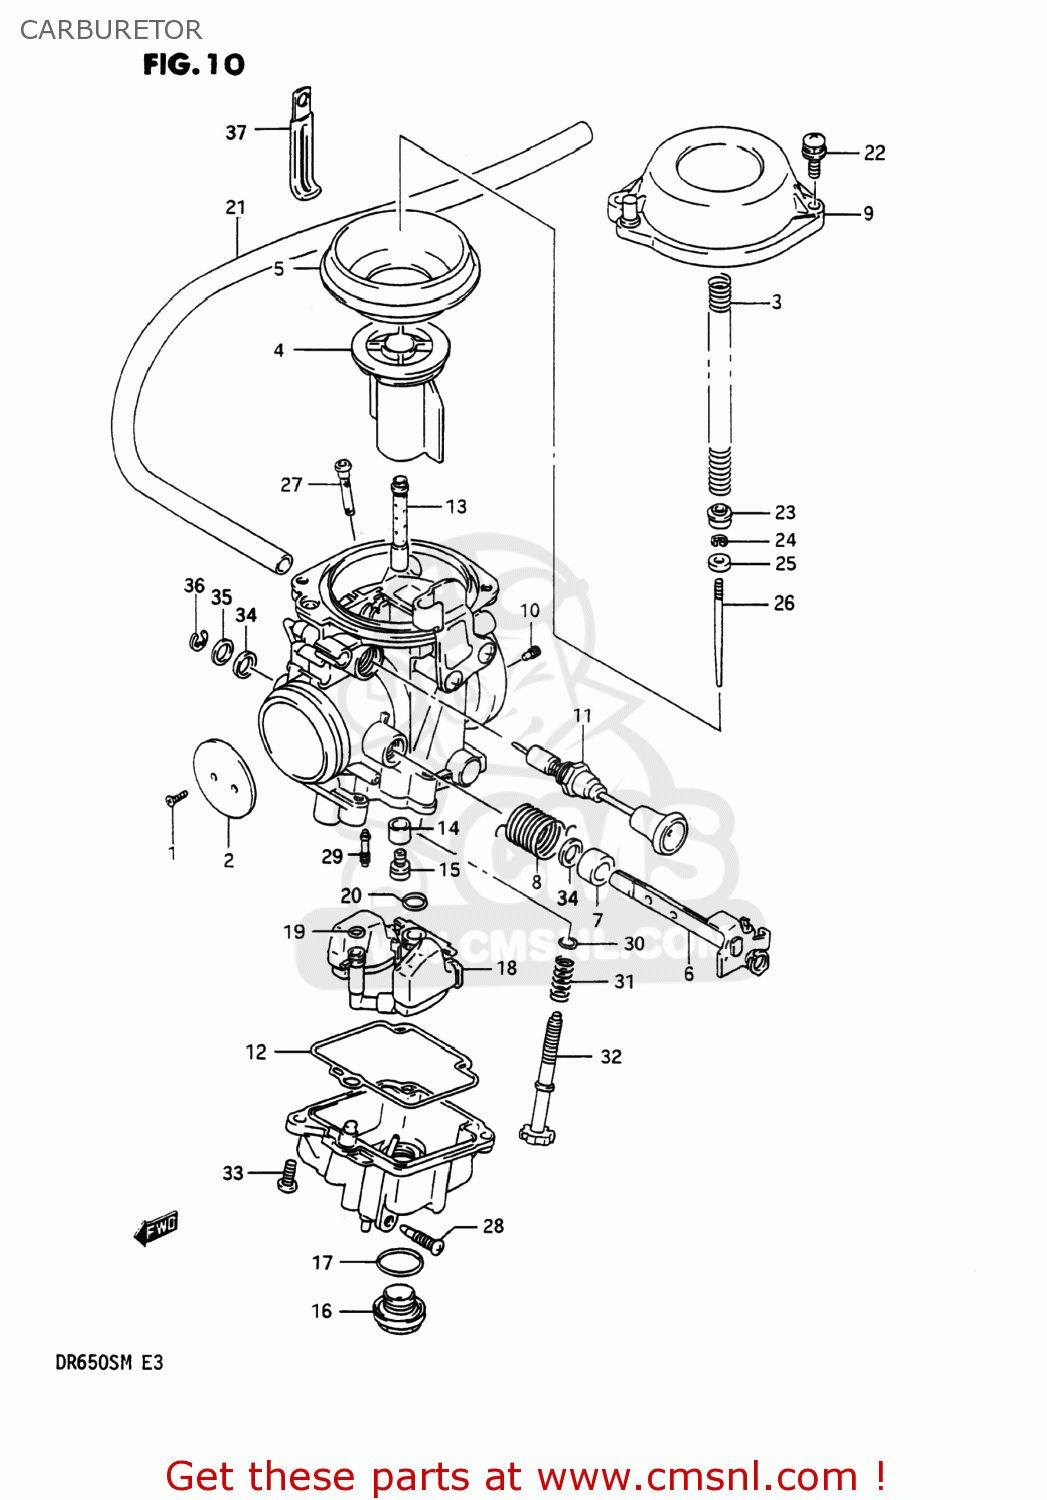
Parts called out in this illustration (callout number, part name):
1	SCREW
2	VALVE,THROTTLE
3	SPRING
4	VALVE,PISTON
5	DIAPHRAGM
6	SHAFT ASSEMBLY,THROTTLE
7	RING
8	SPRING
9	COVER,DIAPHRAGM
10	JET,AIR
11	PLUNGER ASSY
12	GASKET,FLOAT CHAMBER (NAS)
13	JET,NEEDLE (Y-3)
14	RING
15	JET,MAIN (147.5)
16	SCREW,GUIDE
17	O RING,DRAIN PLUG
18	FLOAT/NEEDLE VALVE ASSEMBLY
19	O RING
20	O-RING,NEEDLE VALVE
21	HOSE
22	SCREW
23	RING
24	CLIP,NEEDLE
25	RING
26	NEEDLE JET
27	FILTER
28	PLUG,DRAIN
29	JET,PILOT(47.5)
30	WASHER
31	SPRING
32	SCREW
33	SCREW
34	SEAL
35	GASKET,THROTTLE SHAFT (NAS)
36	E RING
37	CLAMP
